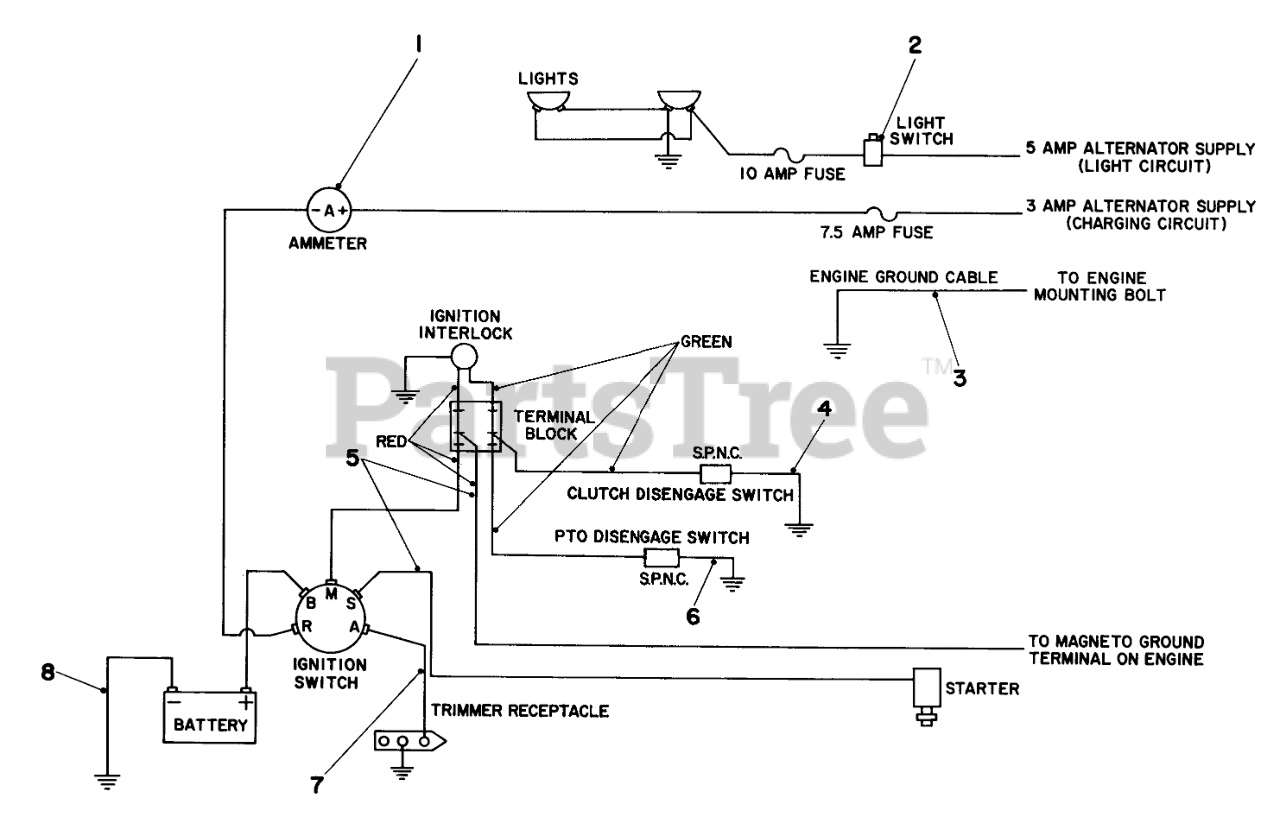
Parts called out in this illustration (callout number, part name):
1	Ammeter
2	Light Switch
3	ENG-GROUND WIRE ASM
4	Wire Assembly
5	Wire Harness
6	Wire Assembly
7	Wire Assembly
8	Wire Assembly
